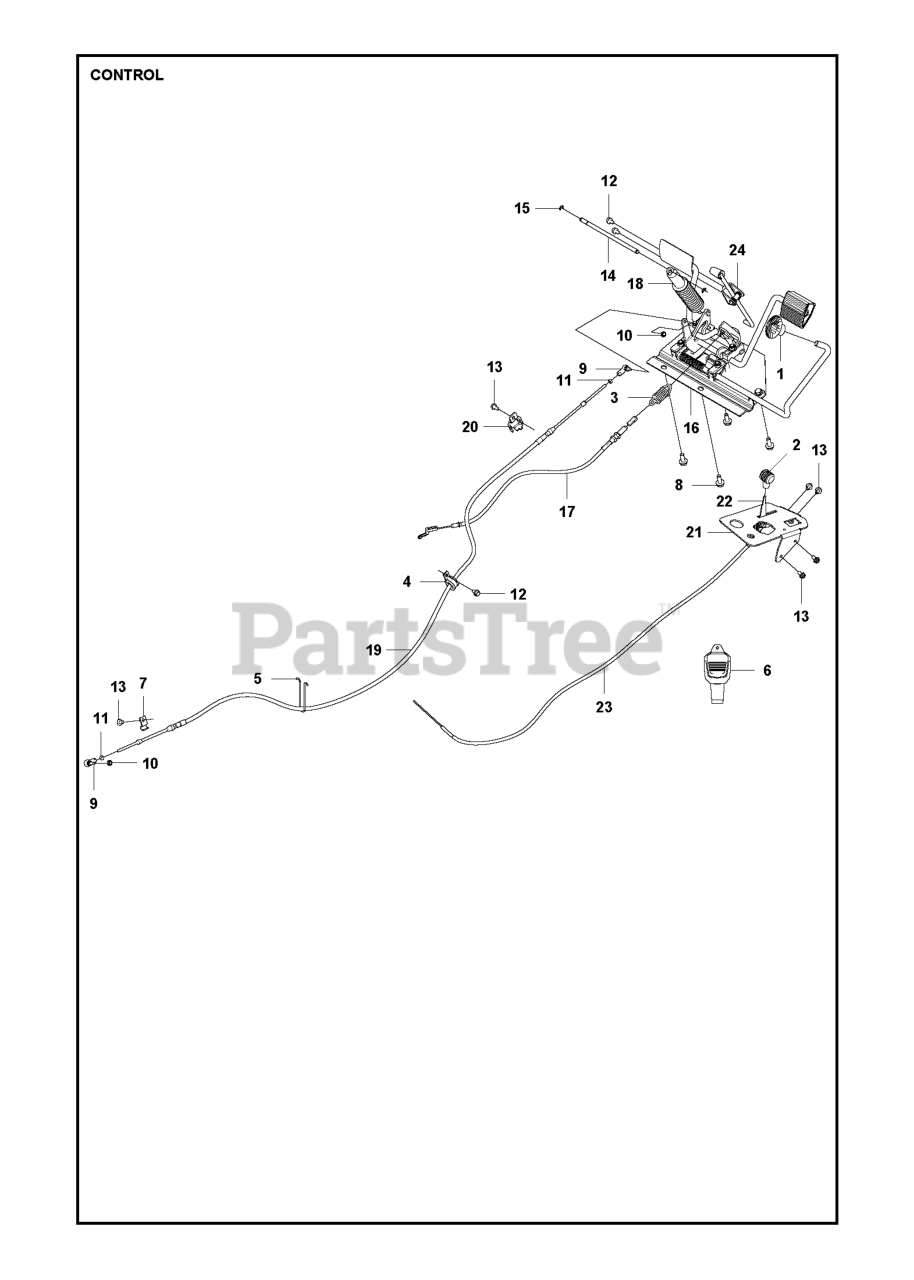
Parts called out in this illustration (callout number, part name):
1	KNOB, THREADED
4	HOSE CLAMP
5	CABLE HOLDER
9	CONNECTOR, BALL JOINT
10	LOCKNUT M6
13	SCREW EHHFM
18	SHOCK ABSORBER
22	THROTTLE CONTROL ASSY SINGLE
24	BRAKE LEVER ASSY
